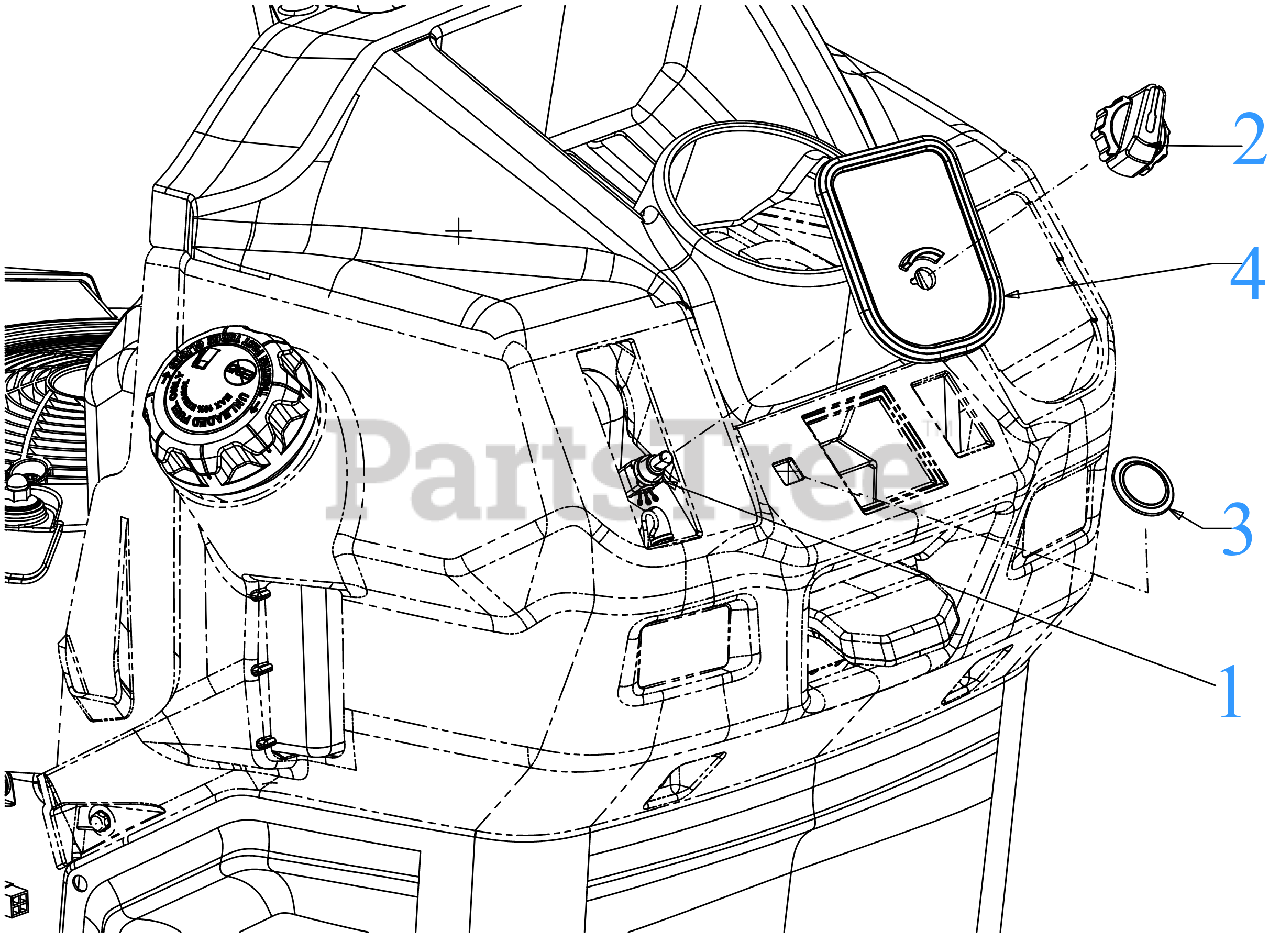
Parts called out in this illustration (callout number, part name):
1	POTENTIOMETER
1	E-GOV POTENTIOMETER KIT
2	CONTROL KNOB
3	CHOKE PLUG
4	DASH COVER PLATE
